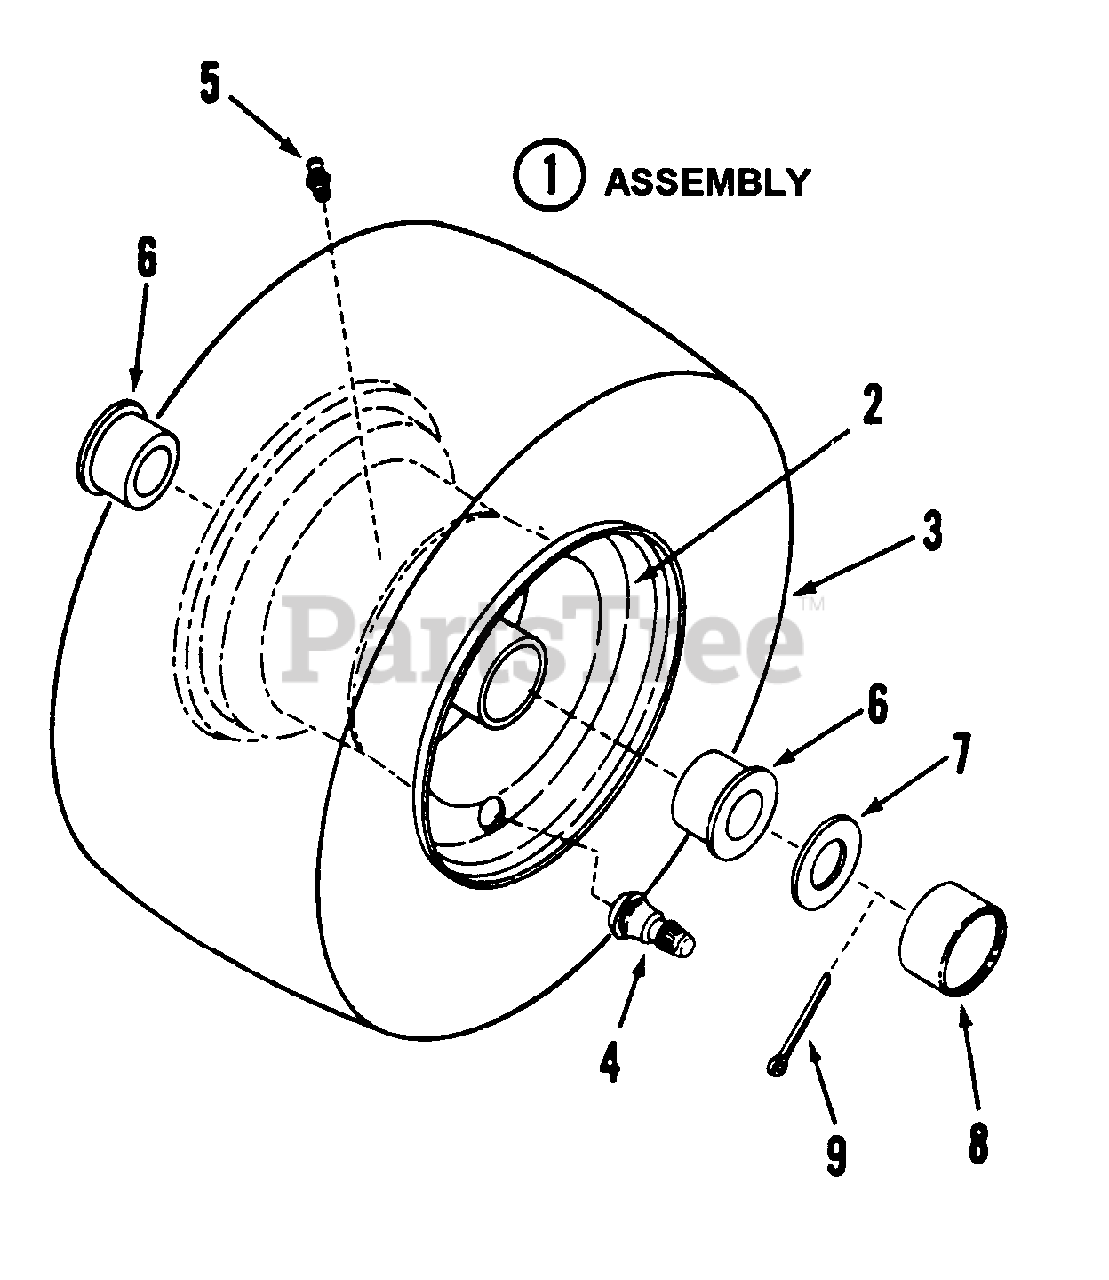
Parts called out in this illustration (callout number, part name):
1	* ASSEMBLY, Front Tire & Rim
2	RIM, LT11 Front Wheel
3	TIRE, 15 x 6.00 x 6
4	VALVE, Air
5	FITTING, Lube 1/4-28 Tapered Thread
6	BEARING, Wheel
7	WASHER, 49/64 x 1-1/2" Flat
8	COVER, Dust
9	PIN, 5/32 X 1" Cotter
